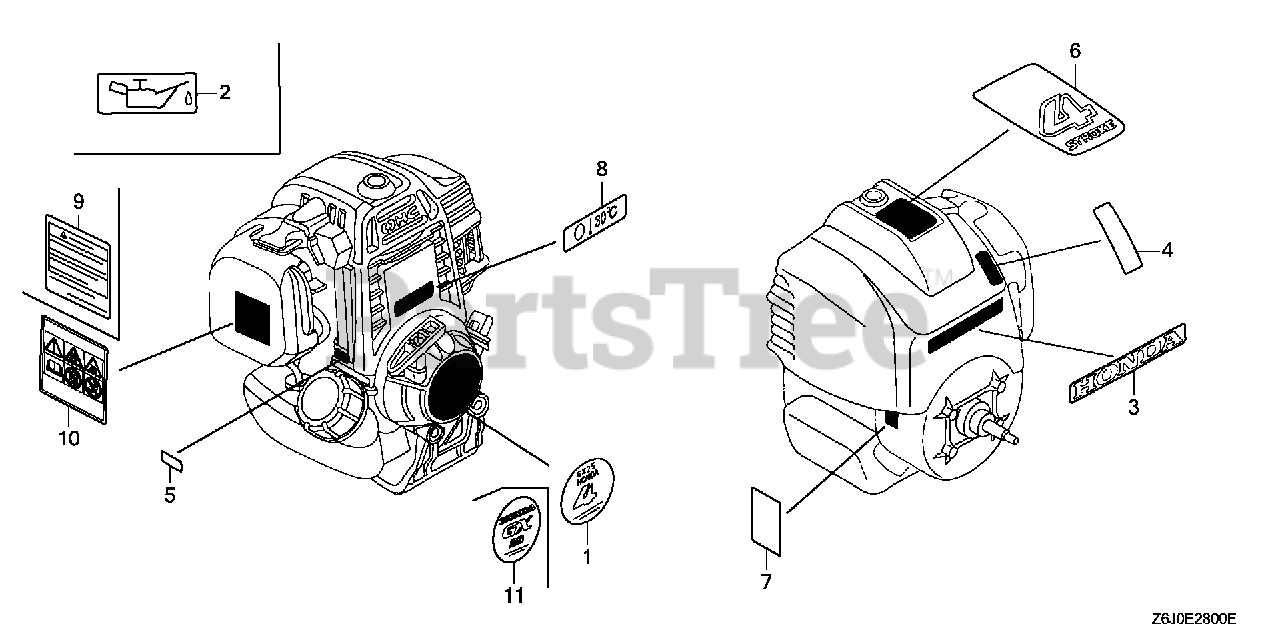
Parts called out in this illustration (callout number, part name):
2	MARK, OIL CAUTION
4	MARK, THROTTLE INDICATION
5	MARK, TYPE (W3)
6	MARK (4-STROKE)
7	LABEL, WARNING (NOT CERTIFIED FOR SALE)
9	MARK, OPERATOR CAUTION (FRENCH)
10	MARK, OPERATOR CAUTION (PICTOGRAPH)
11	MARK, EMBLEM
